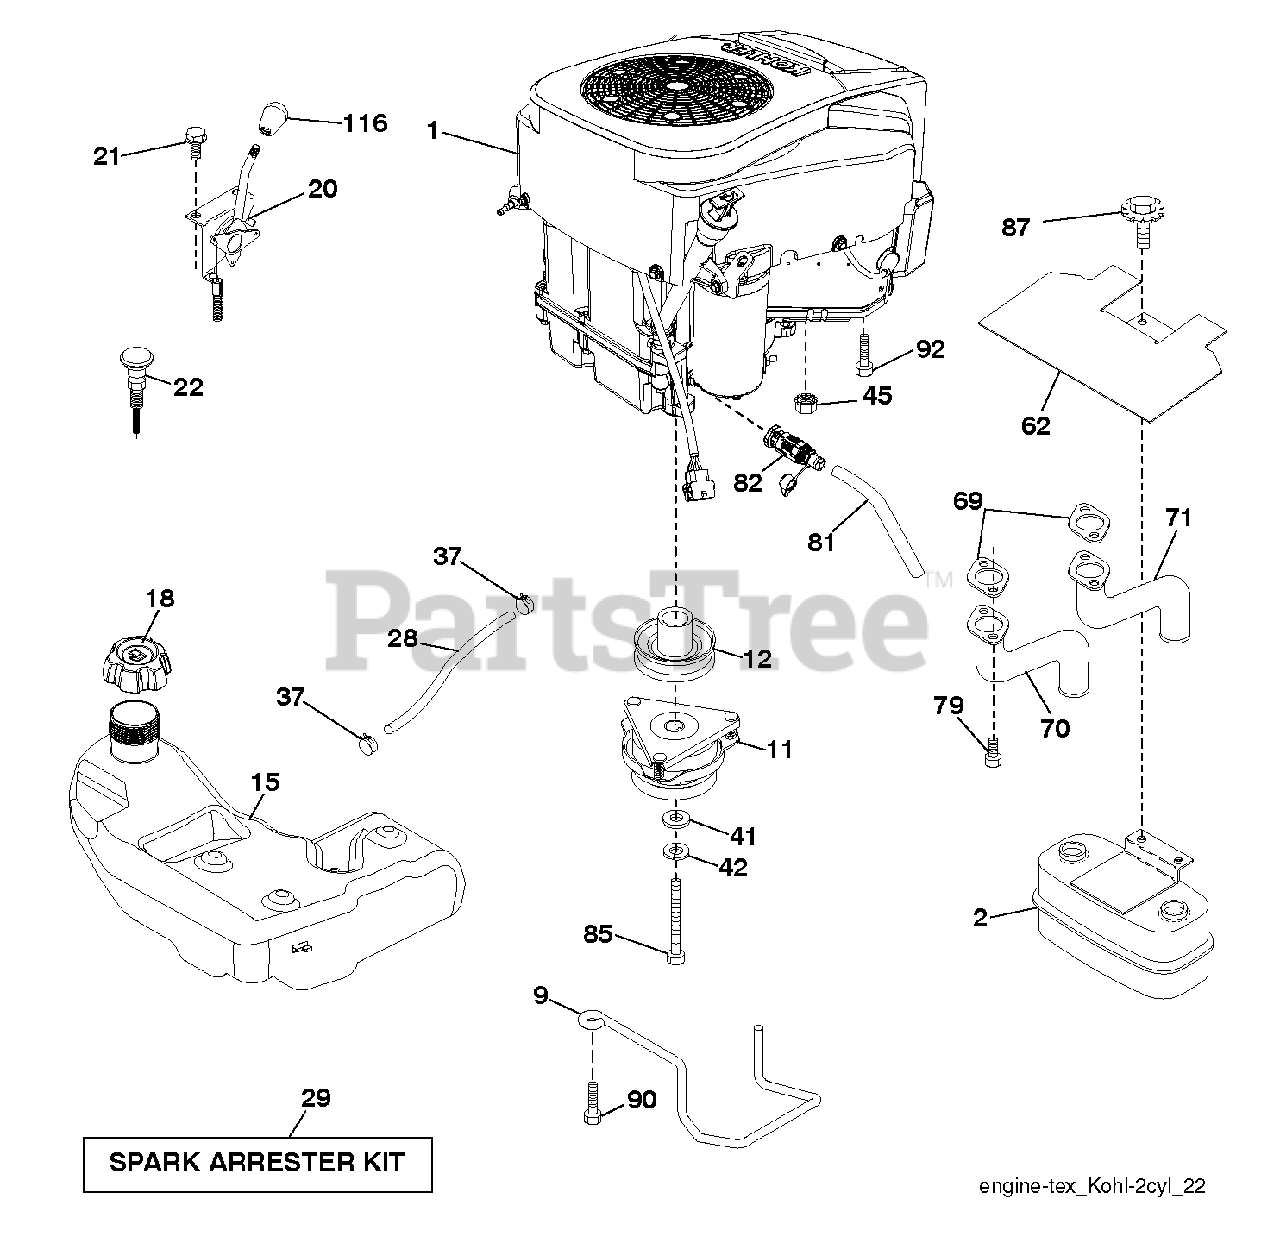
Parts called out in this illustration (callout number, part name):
2	MUFFLER.ASM.TWN.EXTNDED.DFLCTR
9	KEEPER BELT ENGINE
11	CLUTCH.ELECTRIC.LT.48"*
12	PULLEY.ENGINE.TUFFTORQ
15	TANK.ASSY.3.GAL.EPA
18	CAP.ASM.FL.RITCH.3"E10.SYM.498
20	CONTROL.THROTTLE.PRO.KOHLER
21	SCREW.#10 X 0.750.BOS
22	CONTROL, CHOKE
28	LINE.FUEL.64"REAR.EMIS
29	KIT.SPARK ARRESTOR 794945 B&S
37	HOSE CLAMP
42	LOCKWASHER
45	NUT
62	SHIELD.HEAT.MUFFLER
69	GASKET.EXHAUST.KOHL.CV18-CV26
70	PIPE.EXHAUST.LH.CV18/20
71	PIPE.EXHAUST.RH.CV18/20
79	SCREW.SOCKET HD.5/16-1
81	TUBE, DRAIN OIL ASM.
82	VALUE.OIL.DRAIN
85	BOLT HEX 7/16-20X4-1/4"
87	BOLT, 5/16-18 X 1 3/4
90	SCREW 3/8-16X1
92	SCREW 3/8-16X1
116	KNOB - SHIFT
